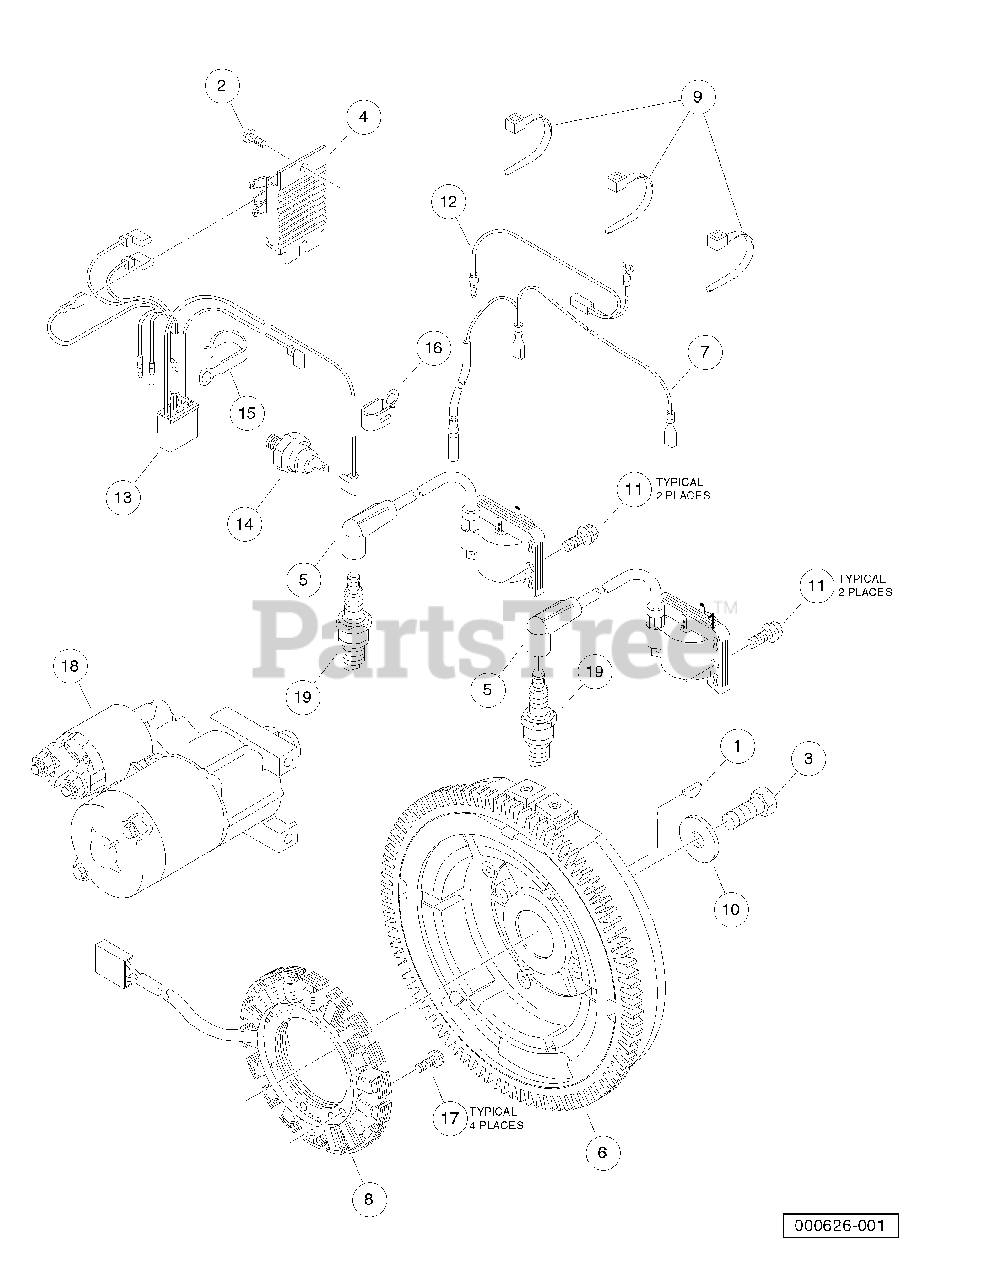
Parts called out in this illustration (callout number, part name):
3	Bolt, Flg, M12 X 1.25 X 30
4	Regulator, Voltage, Fh
5	Coil, Assy, Ignition, Fh
6	Flywheel, Assy, Fh
7	Harness, Regulator, Fh
8	Coil, Charging, Fh
9	Band, Harness, Fh
10	Washer, Flywheel, Fh
11	Bolt, Flanged, M6 X 20, Kaw
12	Harness, Ignition, Fh
13	Harness, Engine, Main, Fh
14	Switch, Oil Pressure, Fh
15	Clamp, Harness, Large, Fh
16	Clamp, Harness, Small, Fh
17	Screw, Pan, Coil Mount, Fh
18	Starter, Electric, Fh680d
19	Spark Plug, BPR2ES
